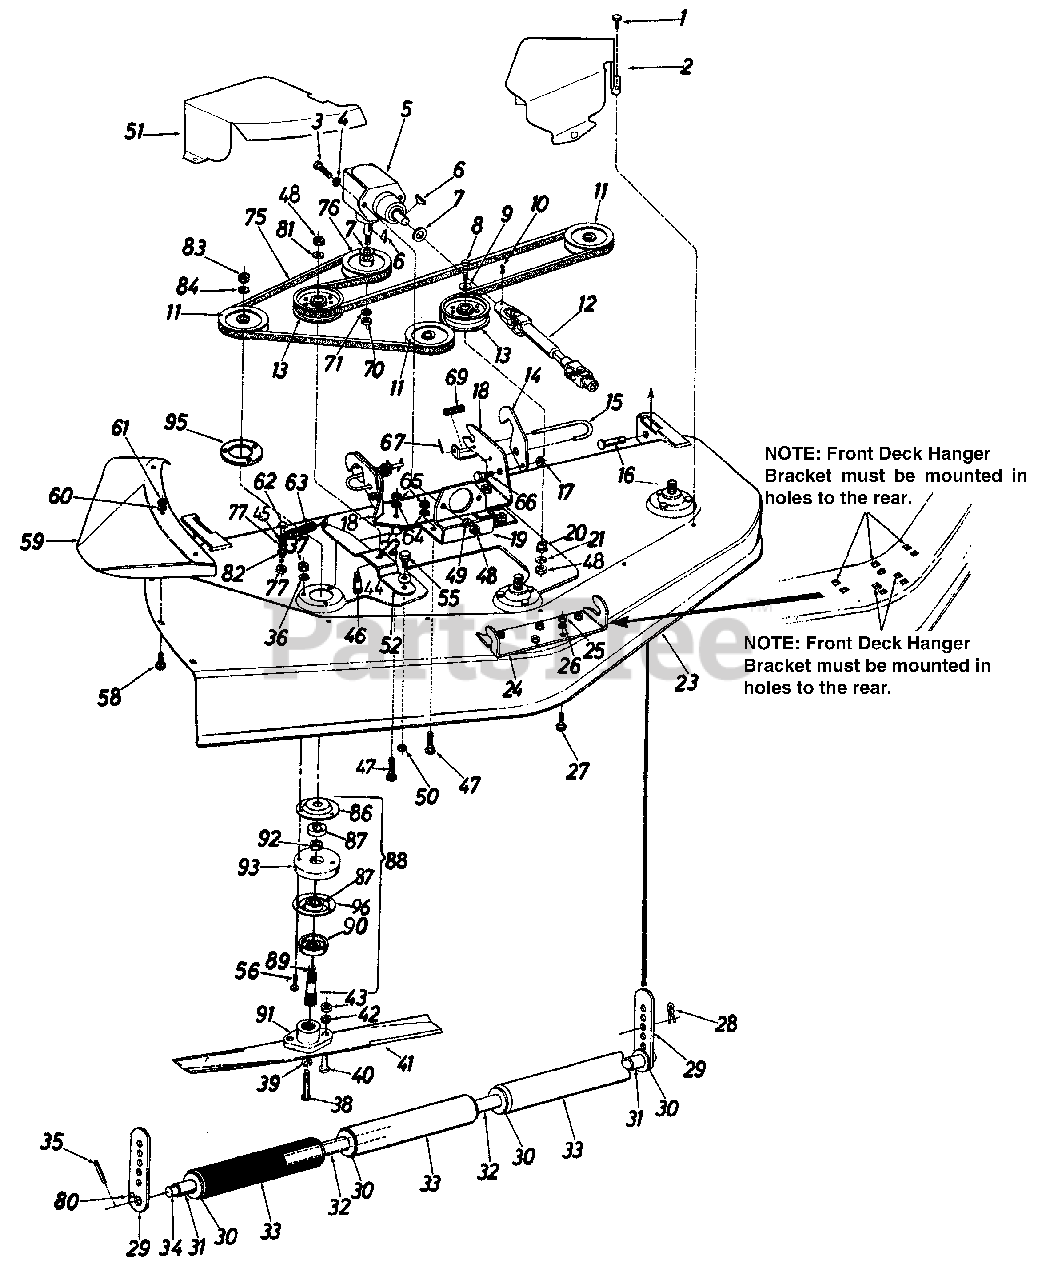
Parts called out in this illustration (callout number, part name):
1	Hex TT-Tap Scr. 1/4-20 x .5" Lg.
3	Hex Bolt 3/8-16 x 1.25" Lg.
4	Ext. L-Wash. 3/8" I.D.
5	Right Angle Drive
6	#9 Hi-Pro Key 3/16 x 3/4" Dia.
7	Fl-Wash. 29/32" I.D.
8	Hex Bolt 3/8-16 x 2.25" Lg.
9	Fl-Wash. 3/8" I.D.
10	Sq. Hd. Set Scr. 3/8-16 x .50"
11	Deck Pulley
12	Universal Drive Shaft Ass'y.
12	Universal Drive Male Half
12	Universal Drive Female Half
13	Deck Idler Pulley
14	Hanger Lock
15	Release Pin
16	Clevis Pin .50" Dia.
17	Hex L-Nut 5/16-18 Thd.
21	L-Wash. 3/8" I.D.
22	Spacer .33" I.D. x .88" O.D.
26	L-Wash. 5/16" I.D.
27	Carriage Bolt 5/16-18 x .75" Lg.
28	Internal Cotter Pin
30	Fl-Wash. .75" I.D. x 1.5" O.D.
31	Spacer .758" I.D. x 1.25" O.D. x .530
34	Roller Shaft
35	Roll Pin 3/16 x 1.25"
36	L-Wash. 5/16" I.D.
37	Hex Cent. L-Nut 5/16-24 Thd.
38	Hex Self-Tap Scr. 3/8-24 x .75" Lg. (Gr. 5)
38	Hex Bolt 3/8-24 x .88" Lg. (Gr. 5)
39	L-Wash. 3/8" I.D. H.D.
40	Hex Bolt 5/16-24 x 1" Lg.
41	Blade 17" (Round hole blade)
42	L-Wash. 5/16" I.D.
43	Hex L-Nut 5/16-24 Thd.
44	Spr. Wash..445" I.D.
45	Fl-Wash. 1/4" I.D.
46	Shld. Scr. .625" Dia. x .96"
47	Carriage Bolt 5/16-18 x 1.5" Lg.
48	Hex Nut 3/8-16 Thd.
49	L-Wash. 3/8" I.D.
50	Hex L-Nut 7/16-14 Thd.
56	Hex Bolt 5/16-24 x 1.5" Lg. (Grade 5)
56	Screw-Rib Neck 5/16-24 x 1.12" Lg.
58	Carriage Bolt 5/16-18 x .75" Lg.
60	L-Wash. 5/16" I.D.
61	Hex Nut 5/16-18 Thd.
62	Hex Bolt 1/4-28 x 1-3/4" Lg.
63	Extension Spring
64	L-Wash. 5/16" I.D.
65	Hex Nut 5/16-18 Thd.
66	Shld. Bolt
67	Roll Pin 1/8" Dia.
69	Compression Spring
70	Hex L-Nut 5/8-18 Thd.
71	L-Wash. 5/8" I.D.
75	V-Belt 1/2"
76	Drive Pulley
77	Hex L-Nut 1/4-28 Thd.
80	Spring Pin Spiral 1/4" Dia. 1.00" Lg.
81	Bell-Wash. 3/8" I.D. x . 87" O.D.
82	L-Wash. 1/4" I.D."
83	Hex Jam Nut 5/8-18 Thd.
84	L-Wash. 5/8" I.D.
86	Bearing Housing
87	Ball Bearing
88	Deck Spindle Assembly 3/4"
88	Deck Spindle Assembly 1"
89	Spindle 3/4"
90	Bearing Shield
91	Blade Adapter 3/4"
91	Blade Adapter 1"
92	Spacer
95	Spindle Reinforcement Plate
96	Open Bearing Housing
96	Bearing Housing w/bearing 741-0919A
